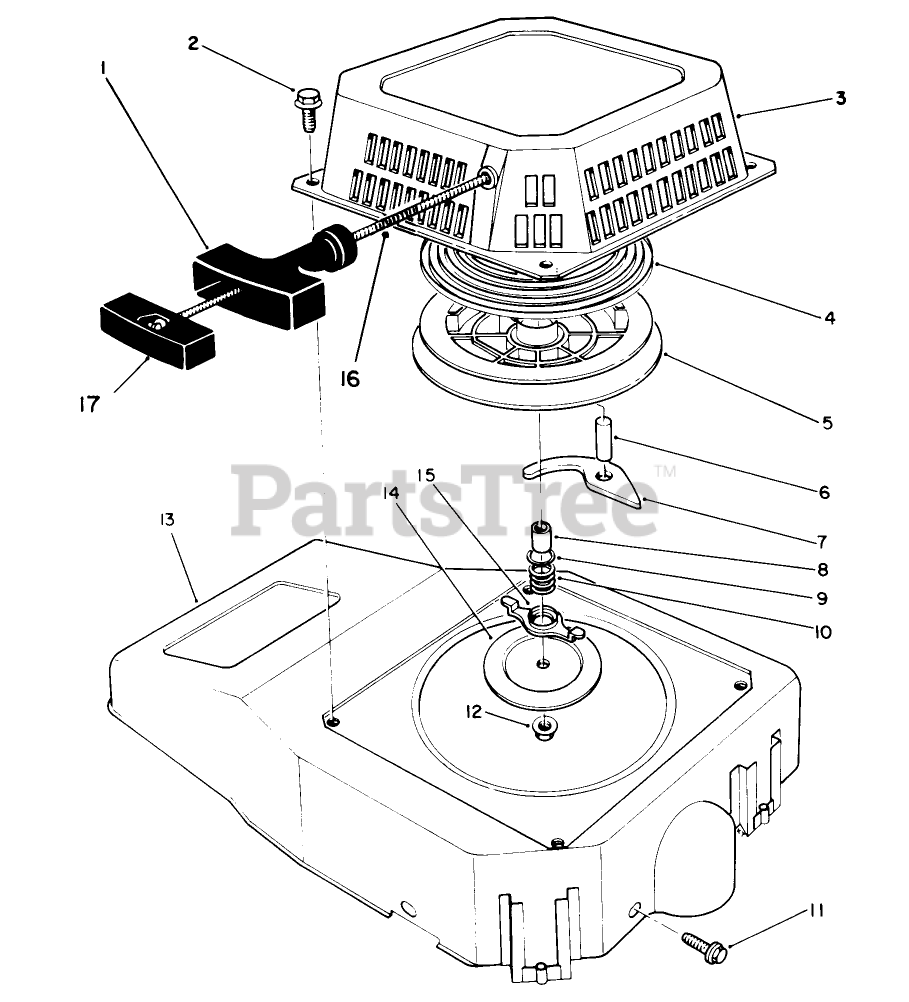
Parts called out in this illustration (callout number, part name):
1	HANDLE
2	SCREW-HHF
3	Case-Recoil
4	SPRING
8	Spacer
9	WASHER
10	Spring-Friction
13	SHROUD
14	PLATE
15	Guide-Paw
16	ROPE-STARTER
17	RETAINER HANDLE
